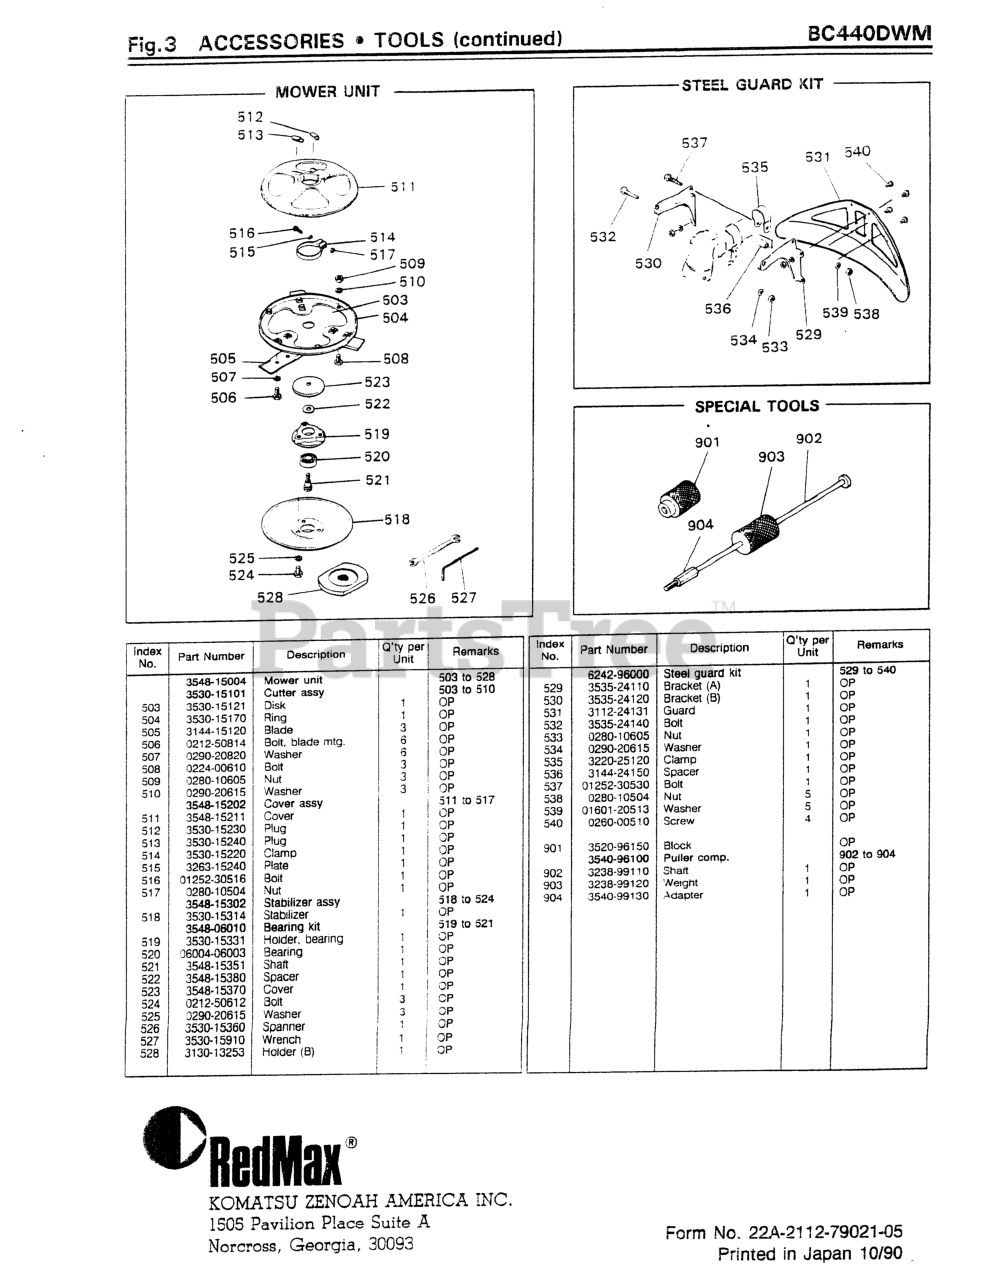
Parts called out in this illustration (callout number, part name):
506	BOLT, BLADE MTG.
507	WASHER, M8 x 20
508	BOLT, M6 x 10
509	NUT, M6 X 5
510	WASHER, M6 X 15
516	BOLT, M5 X 16
517	NUT, M5 X 4
518	STABILIZER
519	BEARING CASE
525	WASHER, M6 X 15
529	BRACKET (A)
533	NUT, M6 X 5
534	WASHER, M6 X 15
537	BOLT, M5 X 30
538	NUT, M5 X 4
539	WASHER, SPRING M4 x 1.3
901	BLOCK (TOOL)
902	SHAFT (TOOL)
904	ADAPTER (TOOL)
